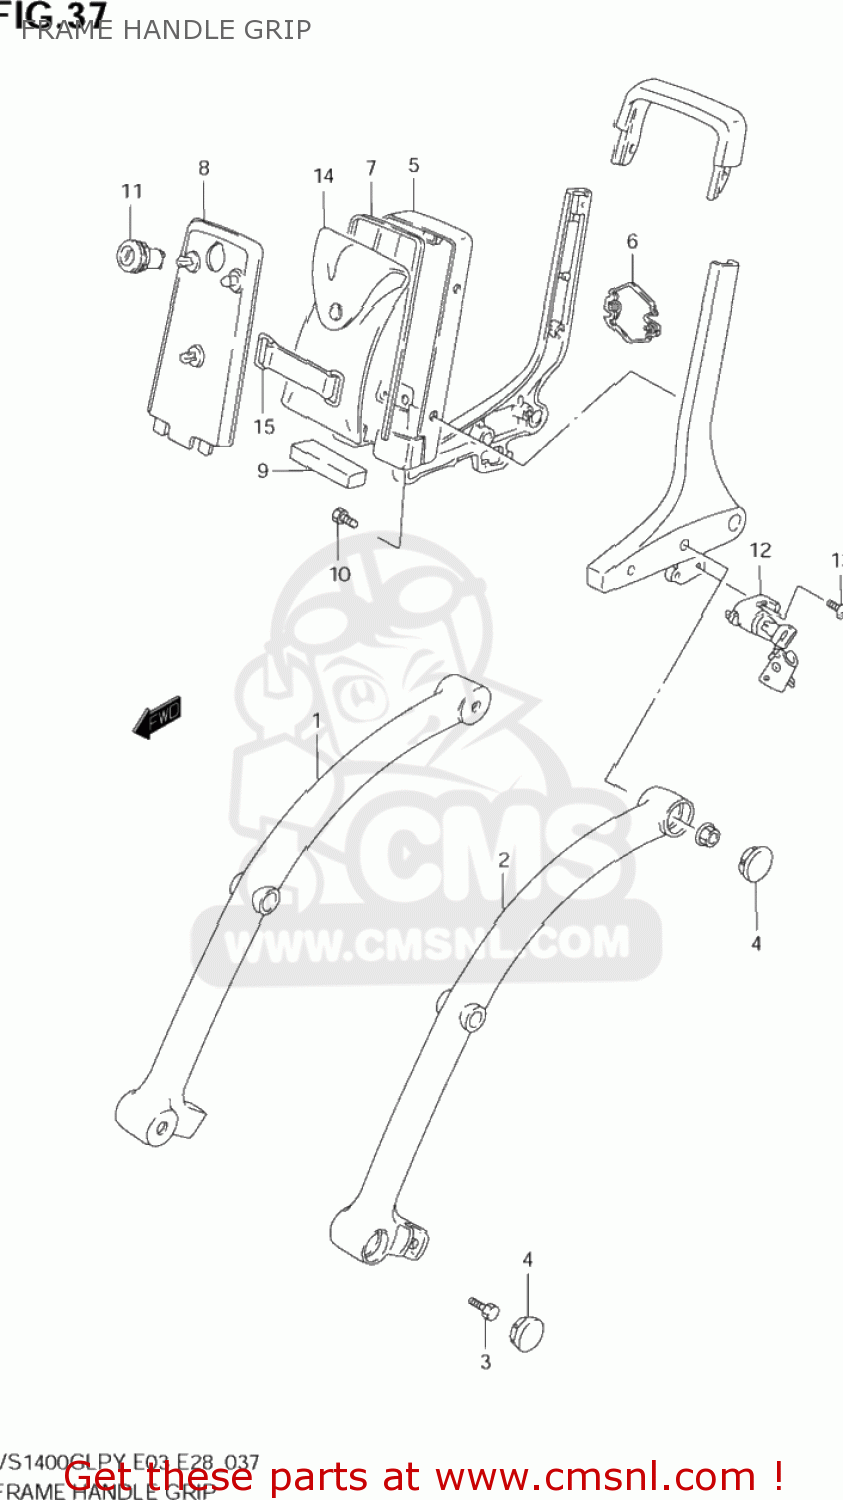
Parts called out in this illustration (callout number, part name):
1	GRIP COMP,FRAME HANDLE
2	GRIP COMP,FRAME HANDLE
3	BOLT
4	CAP,PIPE CO-RIDER GRIP
5	HOLDER,TOOL RR
6	EMBLEM,TOOL HOLDER RR
7	MOLDING,TOOL HOLDER RR
8	HOLDER,TOOL FR
9	CUSHION,TOOL BACK
10	BOLT
11	LOCK SET,TOOL HOLDER
12	LOCK SET,HELMET
13	SCREW
14	TOOL ASSY
15	BAND
16	CARRIER SET,SPORT
